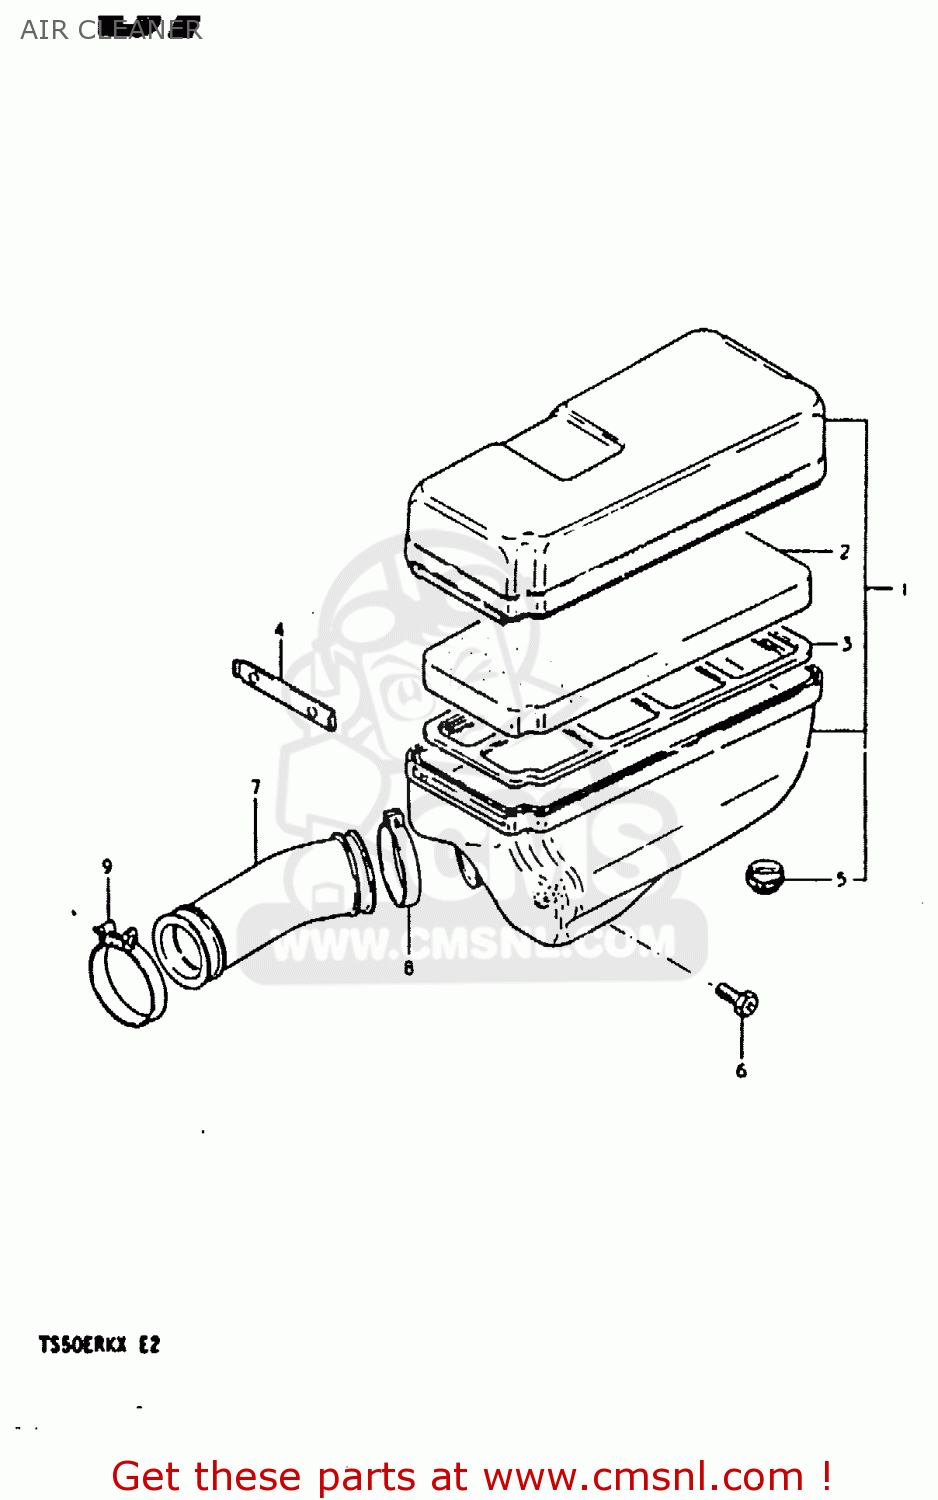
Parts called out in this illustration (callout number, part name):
1	CLEANER ASSY,A
2	FILTER
3	HOLDER
4	SLIDER
5	CAP,DRAIN
6	SCREW
7	TUBE,AIR CLEANER OUTLET
8	CLAMP
9	CLAMP
